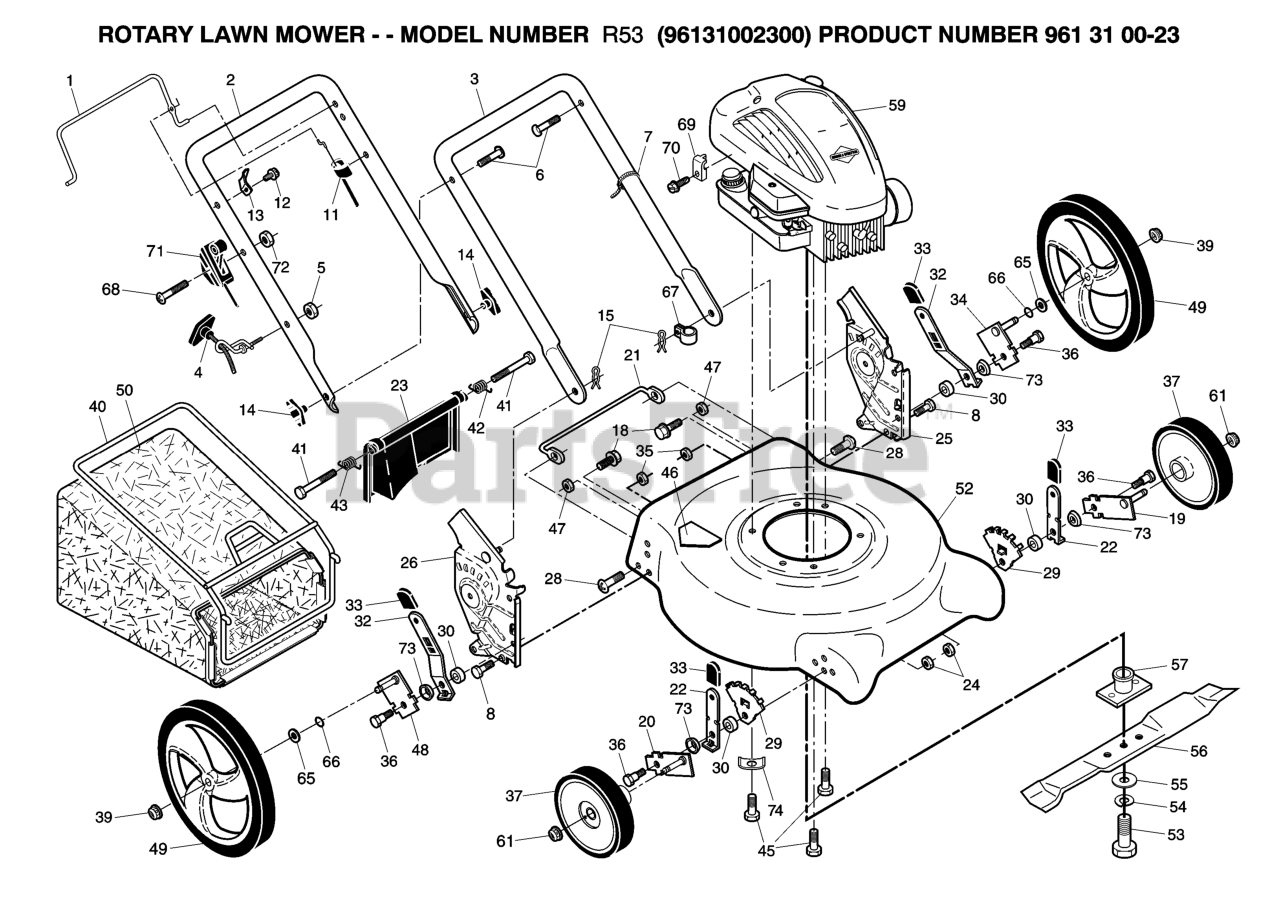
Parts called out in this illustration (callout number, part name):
1	BAIL.MZR.STD.BLACK
2	Upper Handle
3	HANDLE.LOWER.GREY
4	RB GUIDE.ROPE.STD.BLK.ZIN WSL
5	NUT
6	BOLT, HANDLE 5/16-18X1.75
7	TIE GUIDE
8	BOLT.FIN.HEX.5/16-18X3/4
11	ENGINE ZONE CONTROL
13	BRACKET UPSTOP
14	KNOB, DEFLECTOR
15	HAIRPIN COTTER
18	SCREW 1/4X20
19	AXLE ARM ASSY FRONT LH
20	AXLE ARM ASSY FRONT RH
22	SELECTOR SPRING, FRONT
23	REAR DOOR ASSY
24	LOCKNUT 5/16-18
25	BRACKET ASSY.L.H.
26	BRACKET.ASM.HAND.HW.21DOM.RT
29	WHEEL ADJ BRACKET FRONT
30	SPACER.HEIGHT.ADJUSTER
32	SPRING.SEL.EXT.21.DOMED.12/14
34	AXLE ARM ASSY REAR LH
35	LOCKNUT 5/16-18
36	SHOULDER BOLT 5/16-18
37	WHEEL AND TIRE ASSY, REAR
39	NUT.HEX.FLANGE.3/8-16.LOCKNUT
40	FRAME GRASSBAG
42	SPRING.LH.22.REAR.DOOR.EZ.EMPT
43	SPRING.RH.22.REAR.DOOR.EZ.
45	BOLT 3/8-16X1-1/8
46	DECAL.INTERNATIONL.CUTFINGER
48	AXLE ARM ASSY REAR RH
49	RP.WHEEL.12X1.75H 3 SPOKE.RAD
53	SCREW, HEX HD 3/8-24 X 1-3/8
54	LOCKWASHER
55	WASHER,HARDEN
56	BLADE.21.PUSH
57	ADAPTER.BLADE
61	NUT.HEX.FLANGE.3/8-16.LO(3 2)
65	WASHER.FLAT.1/2
66	O-RING..070X.487.NEOPRENE
67	CLIP.CABLE.BLK
69	CABLE CLAMP(ENGINE)
70	SCREW.HEX.HEAD.WASHER.10-16
71	THROTTLE CONTROL
72	NUT
73	WASHER.CURVED.CYLINDRICAL
74	WASHER.ENGINE.BZP
